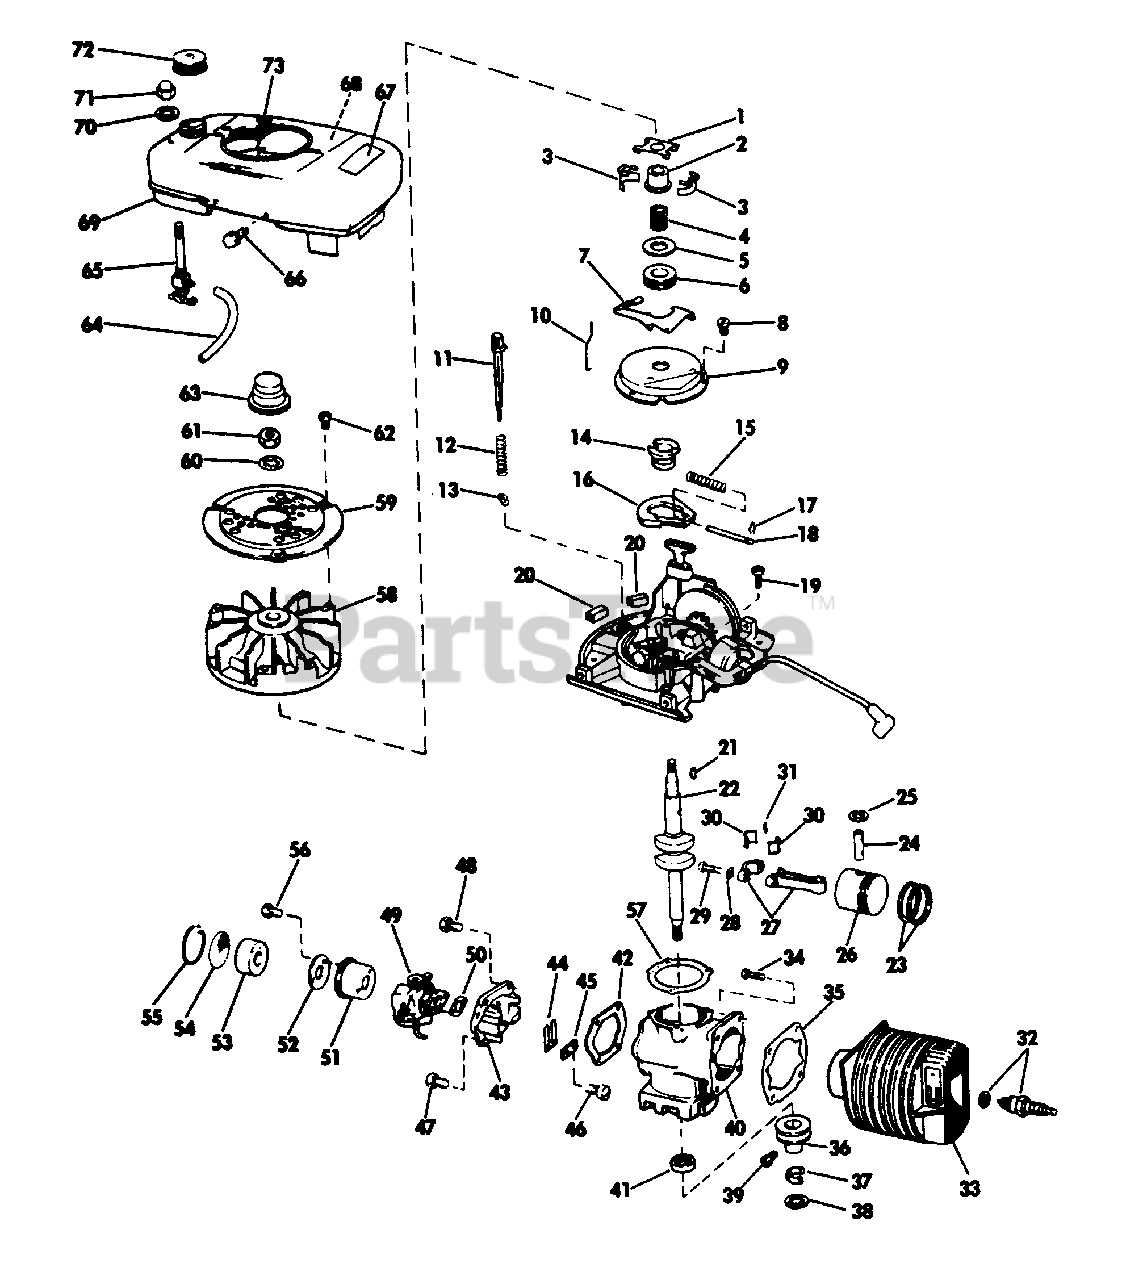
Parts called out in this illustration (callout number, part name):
1	Yoke-Governor
2	Collar-Governor
3	Weight-Governor
4	Spring-Governor
5	Thrust Washer
6	Collar-Thrust
7	Lever-Governor
8	Screw-Attaching Dust Cover
9	Dust Cover
10	Rod-Governor
11	Bar-Shut-Off and Primer
12	Spring-Shut-Off Switch
13	Blade-Switch
14	Cam-Spark Advance
15	Spring-Spark Advance
16	Flyweight-Spark Advance
17	Retainer-Spring
18	Pin-Spark Advance
19	Screw-.Arm. Plate to Crankcase
20	Pad-Rubber, Arm. Plate
21	Key-Crankshaft
22	Crankshaft
23	Ring Set (2 Rings)
24	Wrist Pin
25	Retaining Ring-Wrist Pin
27	Connecting Rod Assy.
28	Lockplate
30	Liners-Connecting Rod
31	Needle Bearing Set
32	Spark Plug and Gasket
33	Cylinder and Sleeve Assembly
34	Screw-Cylinder to Crankcase
35	Gasket-Cyl. to Crankcase
36	Drive Pulley Assembly
37	Clip-Spring
38	Retainer-Push-On
39	Screw-Pulley Drive
40	Crankcase and Seal Assy.
41	Seal-Oil
42	Gasket, Reed Plate to C'case
43	Reed Plate Assembly
45	Plate-Back-Up, Reed
46	Screw-Reed to Reed Plate
47	Screw-Reed Plate to C'case
48	Screw-Reed Plate to C'case
49	Carburetor Assembly
50	Gasket-Carburetor
51	Cup-Air Filter
52	Plate-Back-up, Filter Cup
53	Element-Air Filter
54	Screen-Air Filter (Large)
55	Clip-Air Filter
56	Screw-Air Filter
57	Gasket-Crankcase to Armature Plate, .005 In.
57	Gasket-Crankcase to Armature Plate, .010 In.
58	Flywheel Assy.
59	Screen Flywheel
60	Lockwasher-Flywheel
61	Nut-Flywheel
62	Screw-Thd. Cutting
63	Cap-Flywheel
64	Gas Line
65	Shut-Off Valve
66	Screw-Shroud to Armature Plate
67	Decal-Instruction
68	Decal-LAWN-BOY
69	Gas Tank Assy.
70	Lockwasher
72	Cap
73	Shroud and Shield Assy.
